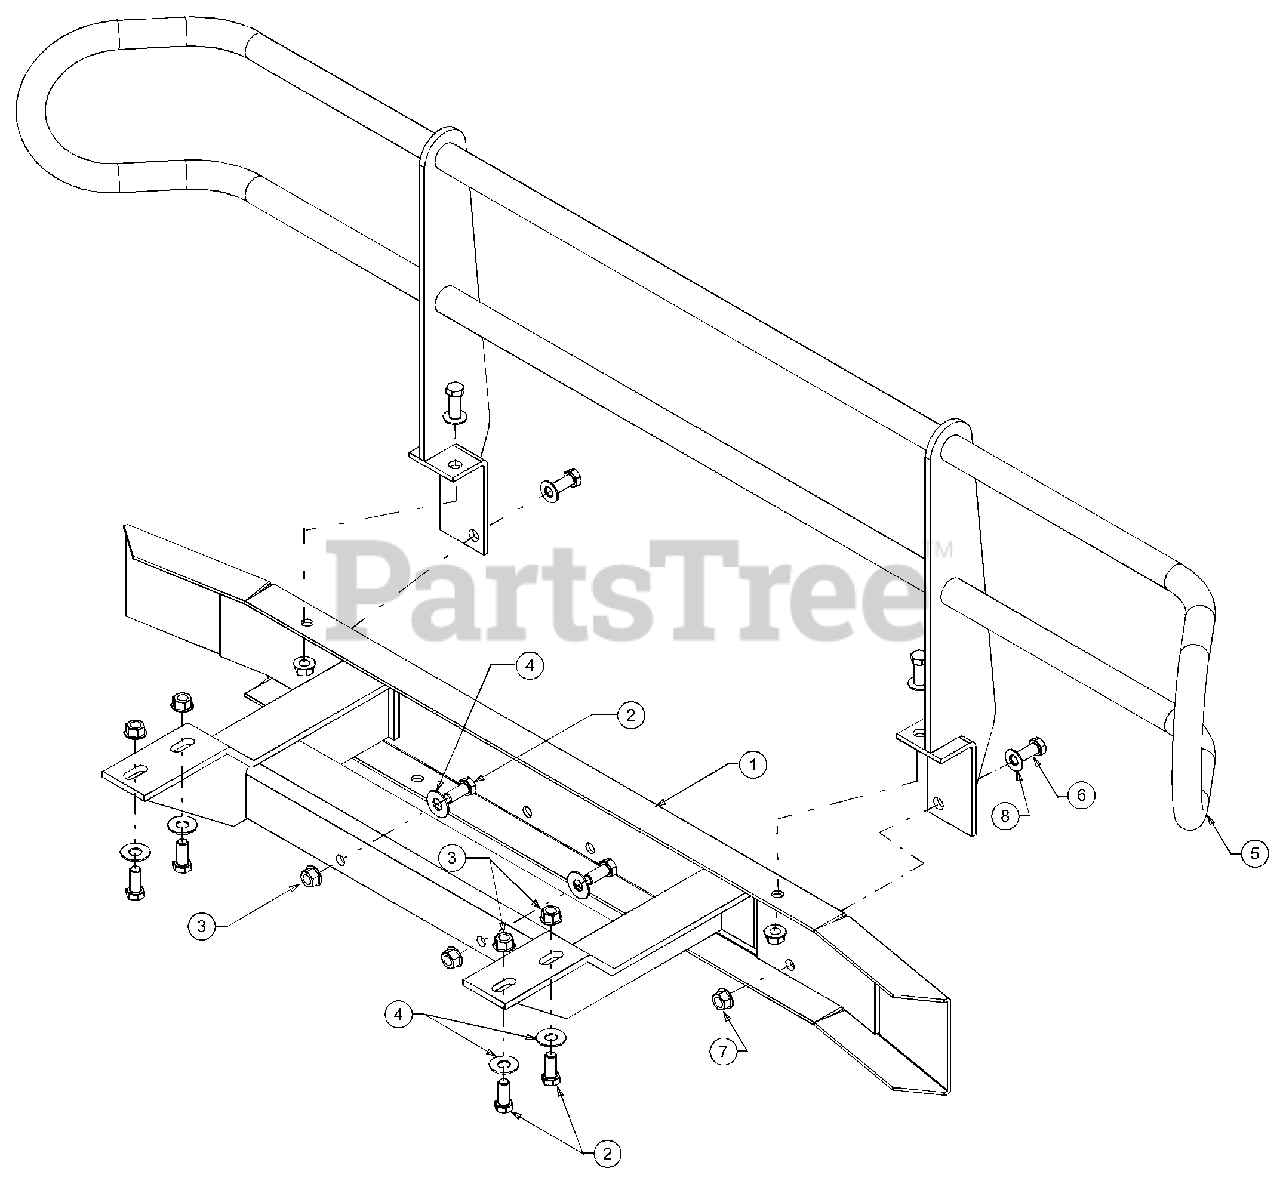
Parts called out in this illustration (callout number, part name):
3	Nut, Flange Lock, 3/8-16
4	Washer, Flat, .444 x 1.0 x .057
5	Guard, Brush
6	Screw, Hex 3/8-16 x 1.00 GR 5
7	Nut, Flangelock 3/8-16
8	Flat Washer,.406 ID x 810 OD x.051
